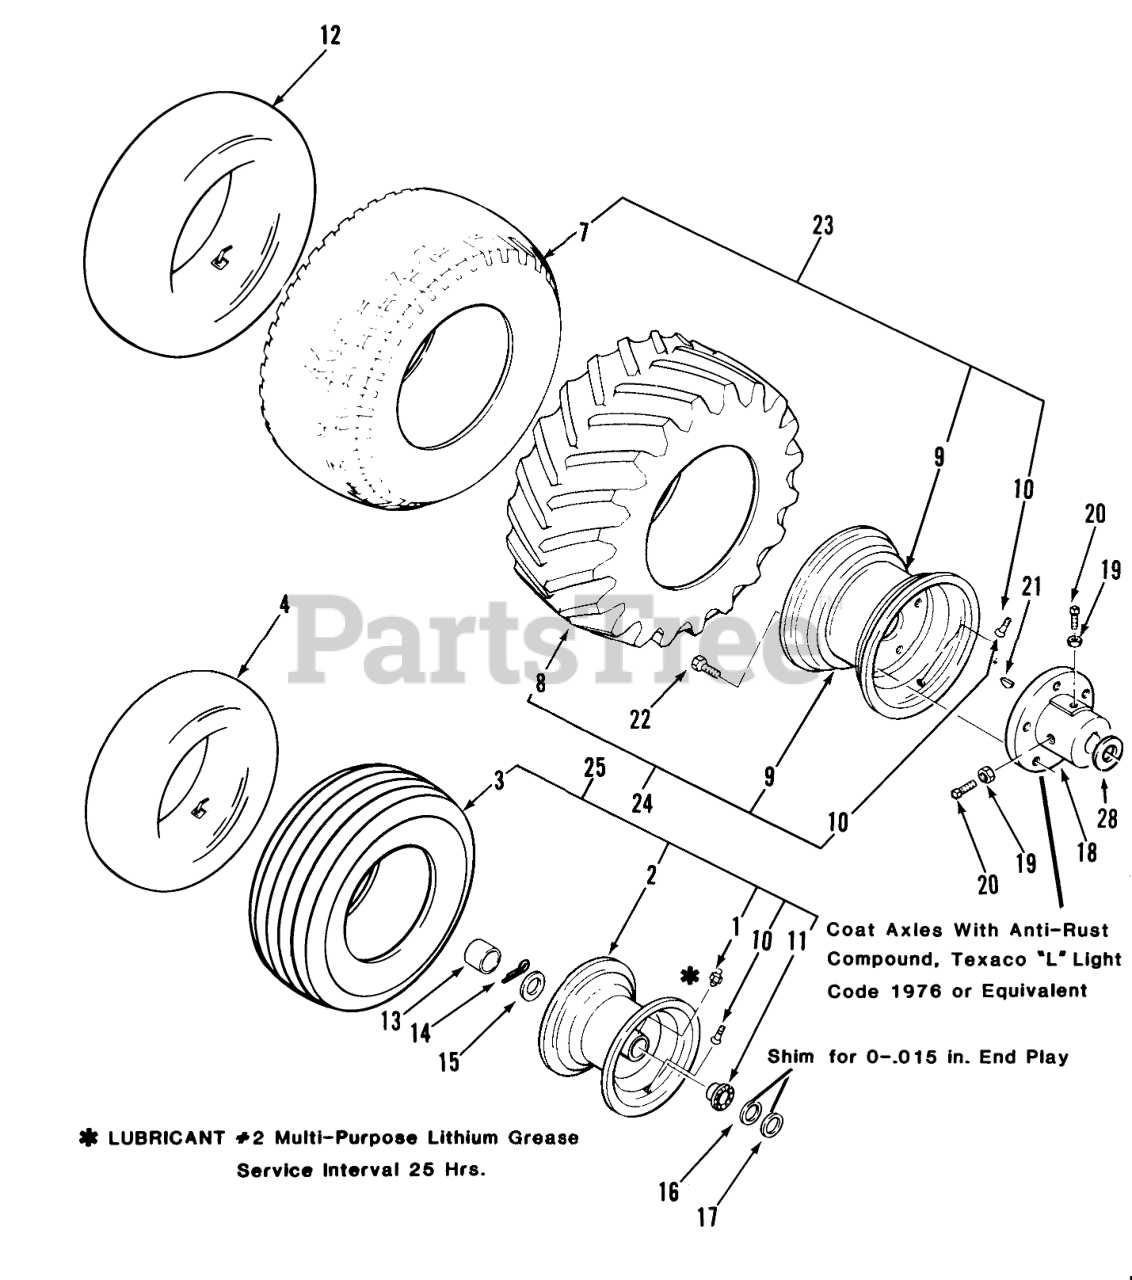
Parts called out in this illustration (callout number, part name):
1	ZERK-GREASE
2	Front Wheel (includes Item 1, 10, 11) 308, 310
3	TIRE15 X 6.00-6
7	TIRE 22 X 7.50-12
8	Tire-Cleat, Rear
9	WHEEL
10	VALVE
11	BEARING-WHEEL
12	INNER TUBE
13	HUB CAP-FLAT BLACK
14	COTTER PIN-4
15	WASHER-WHEEL
16	WASHER
17	WASHER-SHIM
18	Hub Rear
19	Nut
20	Screw-Set
21	KEY-WOODRUFF
22	Lug Nut
23	Rear Wheel & Tire Assy 308
24	ASSY WHEEL & TIRE
25	Front Wheel & Tire Assy 310
